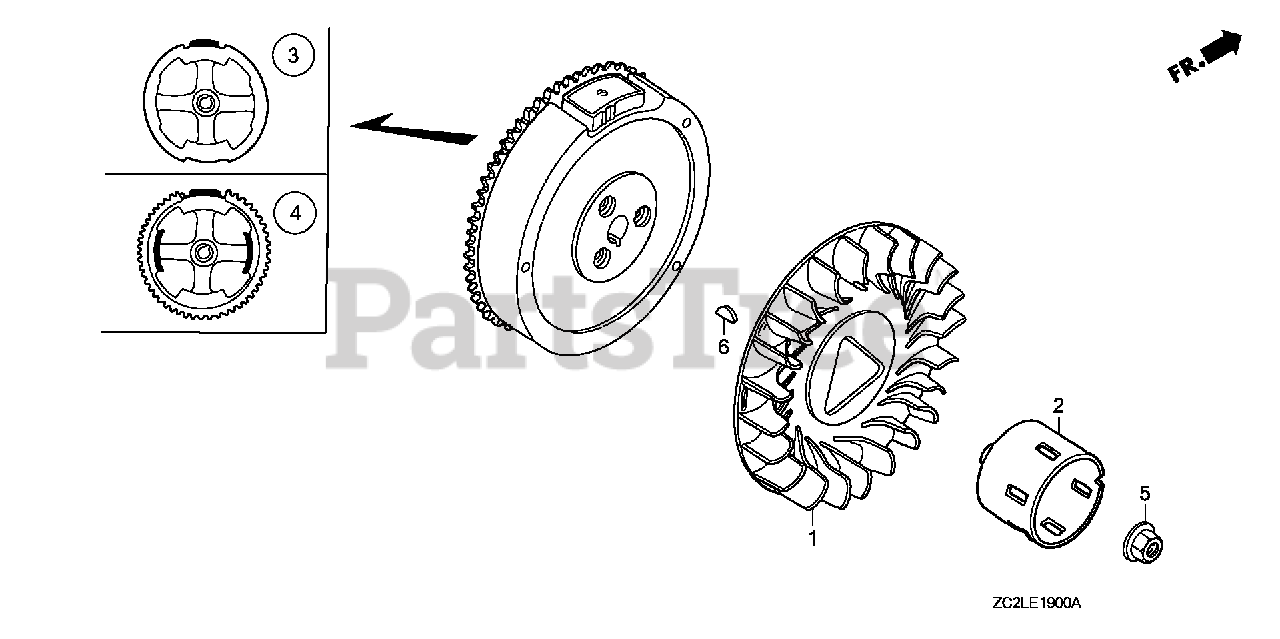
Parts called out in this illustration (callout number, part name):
1	FAN, COOLING
2	PULLEY, STARTER
5	NUT, SPECIAL (16MM)
6	KEY, SPECIAL WOODRUFF (25X18)
